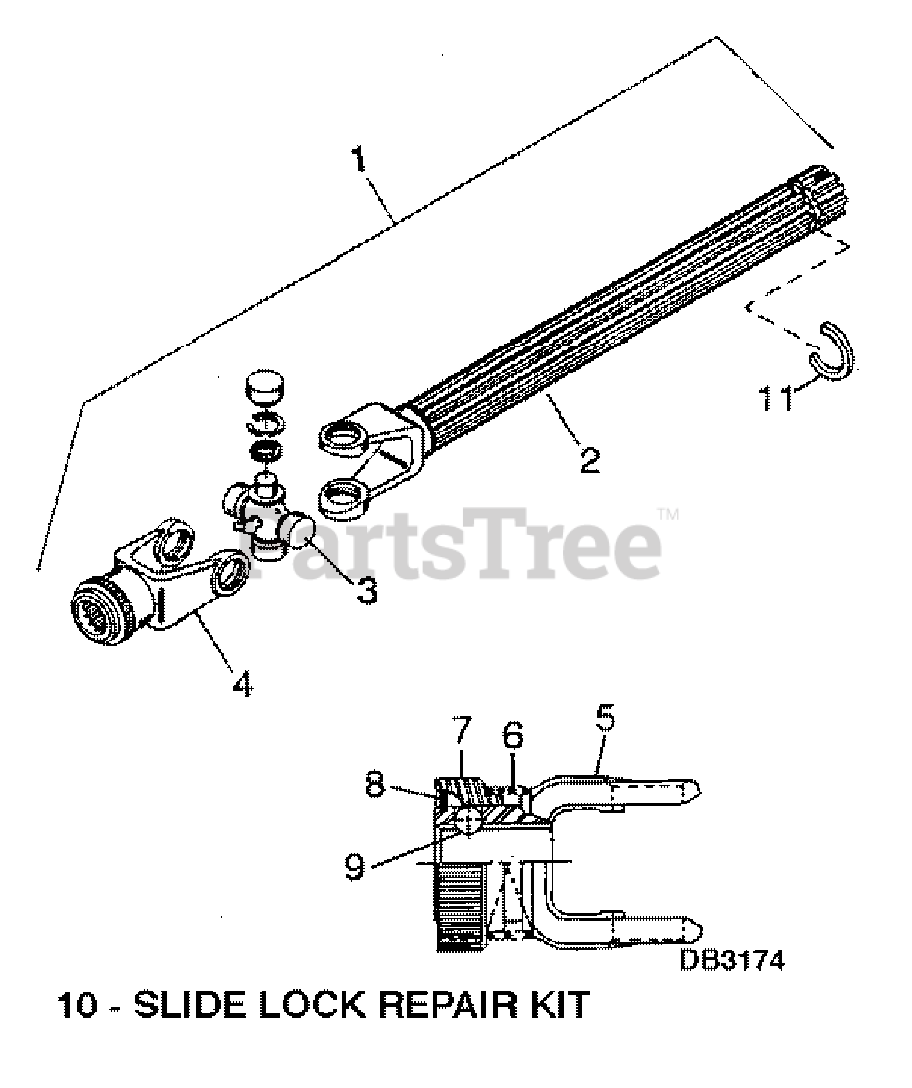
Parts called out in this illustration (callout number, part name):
1	Rear half U-joint drive
2	Yoke and shaft
3	U-Joint repair kit - #0600
4	Slide collar yoke assembly, 15-tooth #0600
5	Slide collar yoke Not Sold Separately
6	Spring
7	Slide collar
8	Snap ring
9	Steel ball
10	Slide lock repair kit #0600
11	.080 x .773 External retaining ring
